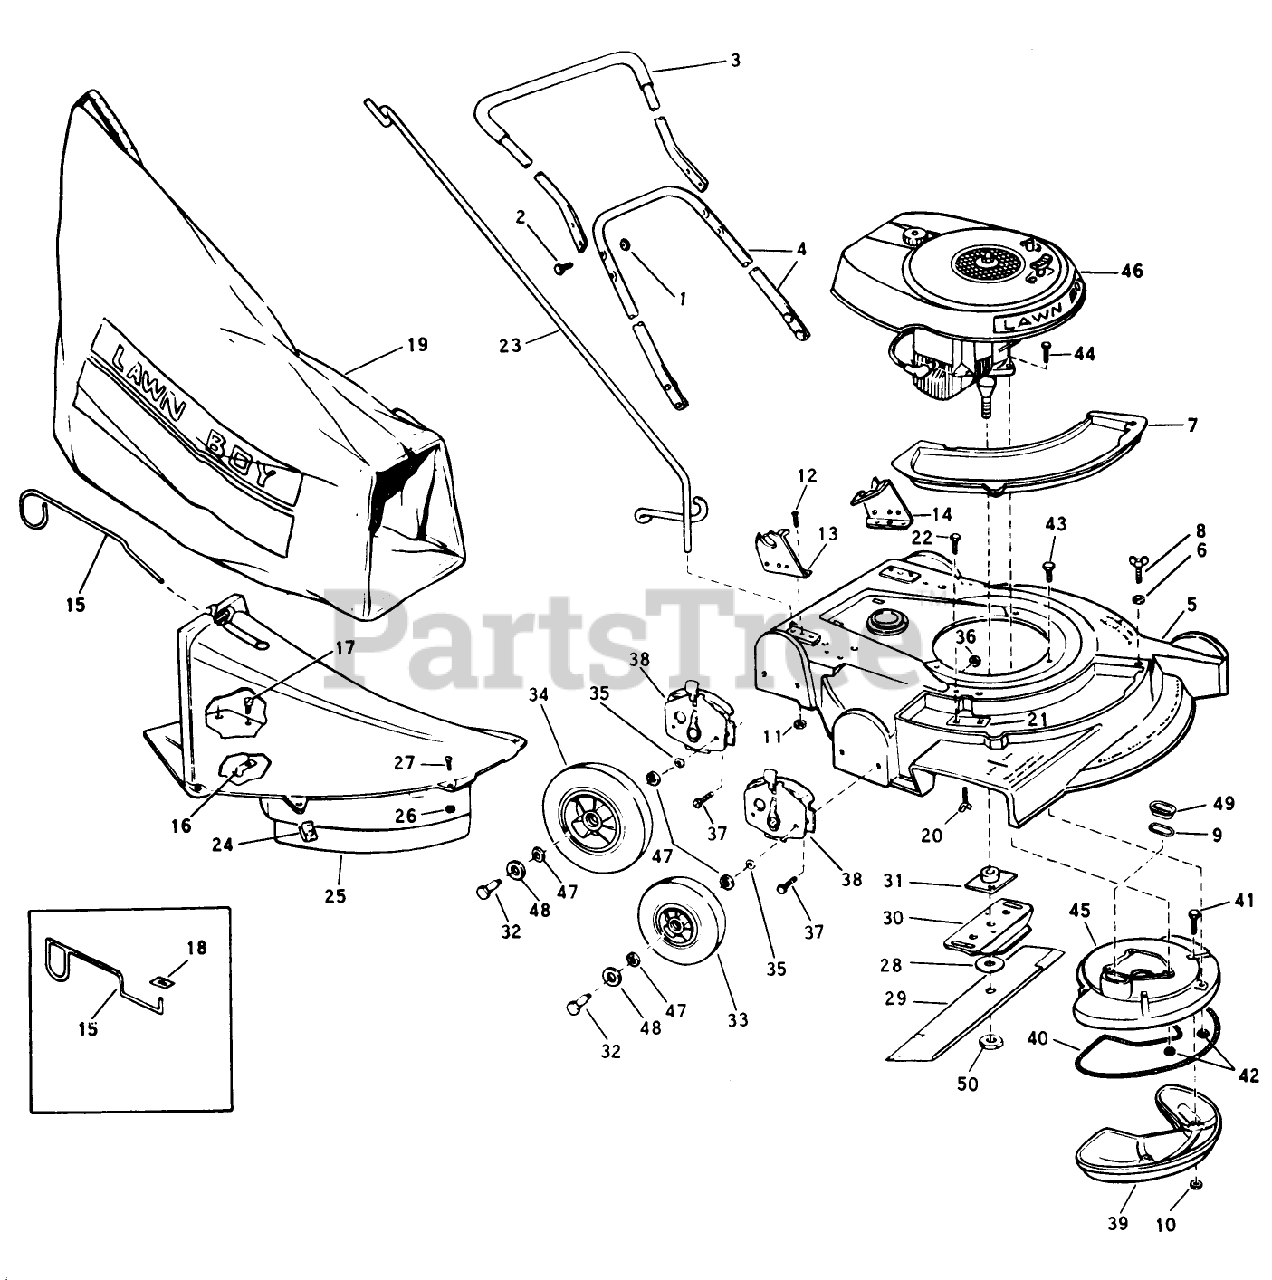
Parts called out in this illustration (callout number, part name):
3	Handle Grip Assy. Top
9	GASKET S
10	LOCKNUT E
12	SCREW S
19	89802 LB WHOLE GOODS
24	SPEED NUT ARDEN
25	Chute Skirt Assembly (Includes Hardware)
26	NUT S
31	PLATE AND COLLAR ASM
32	BOLT WHEEL
35	WASHER WROUGHT
50	NUT-BLADE
